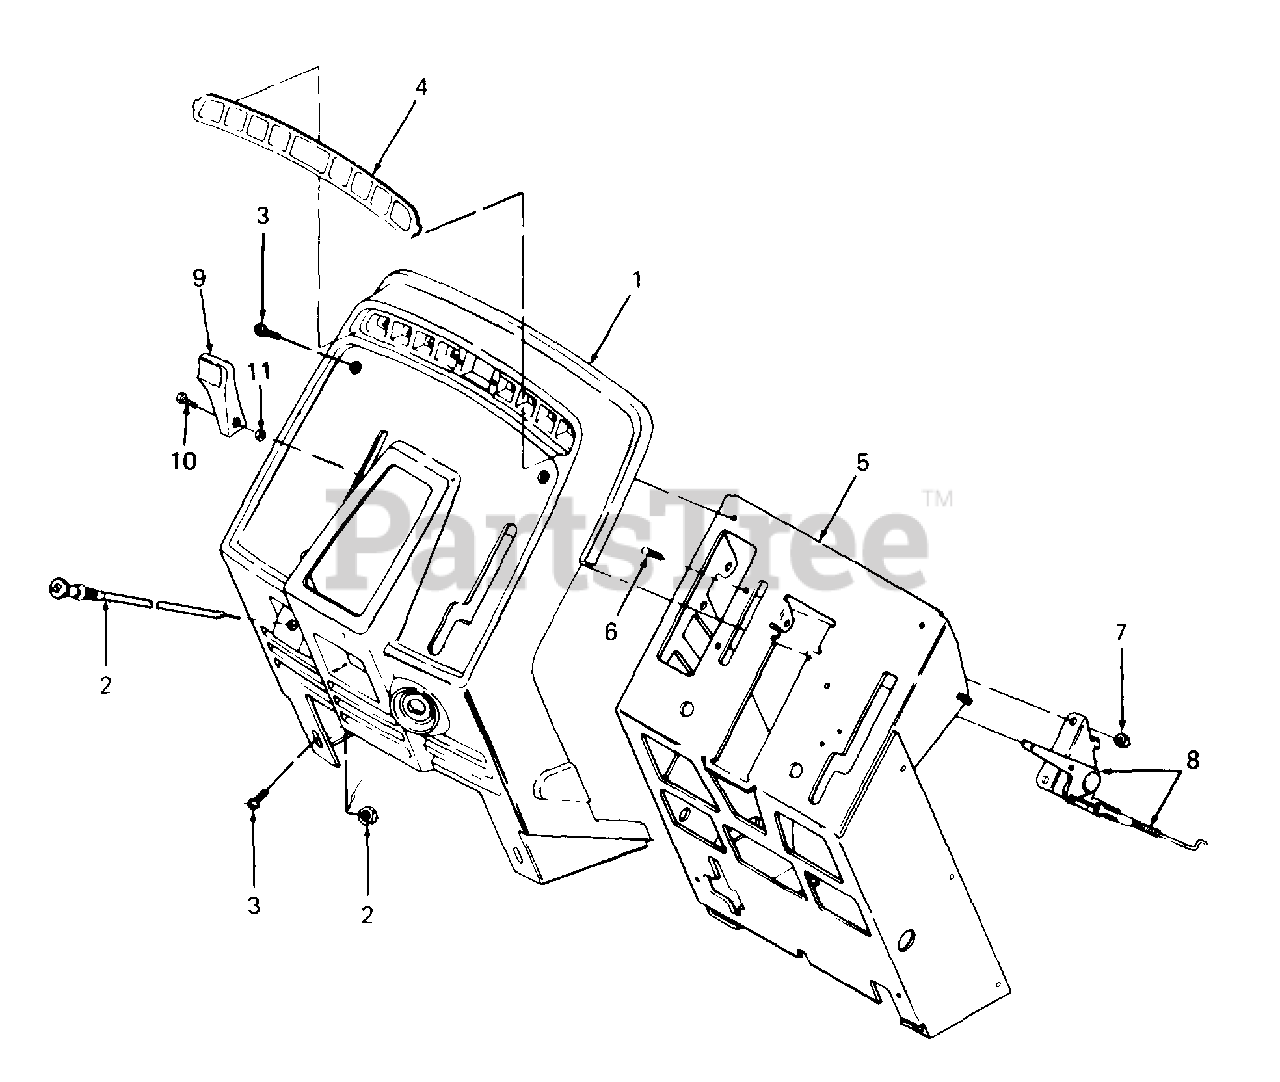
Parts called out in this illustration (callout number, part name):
1	Panel, Instrument
2	Choke Cable w/Nut
3	Screw, Pan Hd Cutting, #10-24 X.75 Lg
4	Label, Dash
7	Nut, Hex Keps, #10-32
8	Control, Throttle
9	Knob, Throttle
10	Screw, Cross Rec Truss Hd, #8-32 X .38 Lg
11	Nut, 8-32
